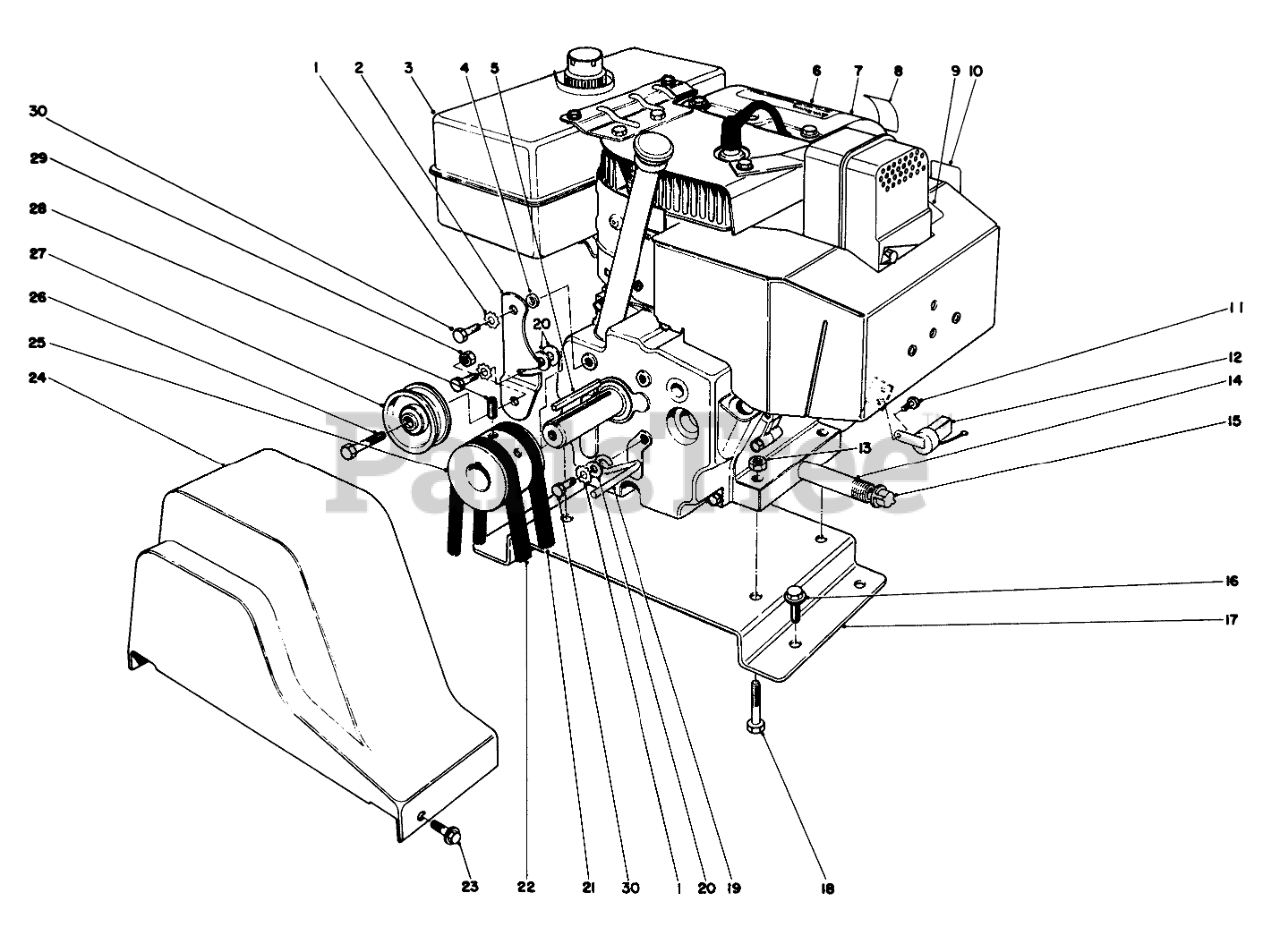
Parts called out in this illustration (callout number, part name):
1	WASHER-LOCK
2	ENGINE IDLER ARM
3	Fuel Tank w/Cap
4	SPACER
6	DECAL - DANGER
8	DECAL-PRIMER
9	HOT SURFACE DECAL
10	CHOKE DECAL
11	Screw-Thread Forming
12	INTERLOCK MODULE
13	NUT-LOCK, NI
14	NIPPLE-PIPE
15	CAP-PIPE
16	SCREW-HWHTF
17	Plate ngine Mounting
18	SCREW-HH
19	BELT RETAINER
20	WASHER-PLAIN
21	V-BELT
22	V-BELT
23	SCREW-HWH
24	BELT GUARD
25	ENGINE PULLEY
26	SCREW-HH
27	PULLEY-IDLER
28	SETSCREW
29	NUT-LOCK, NI
30	SCREW-HH
